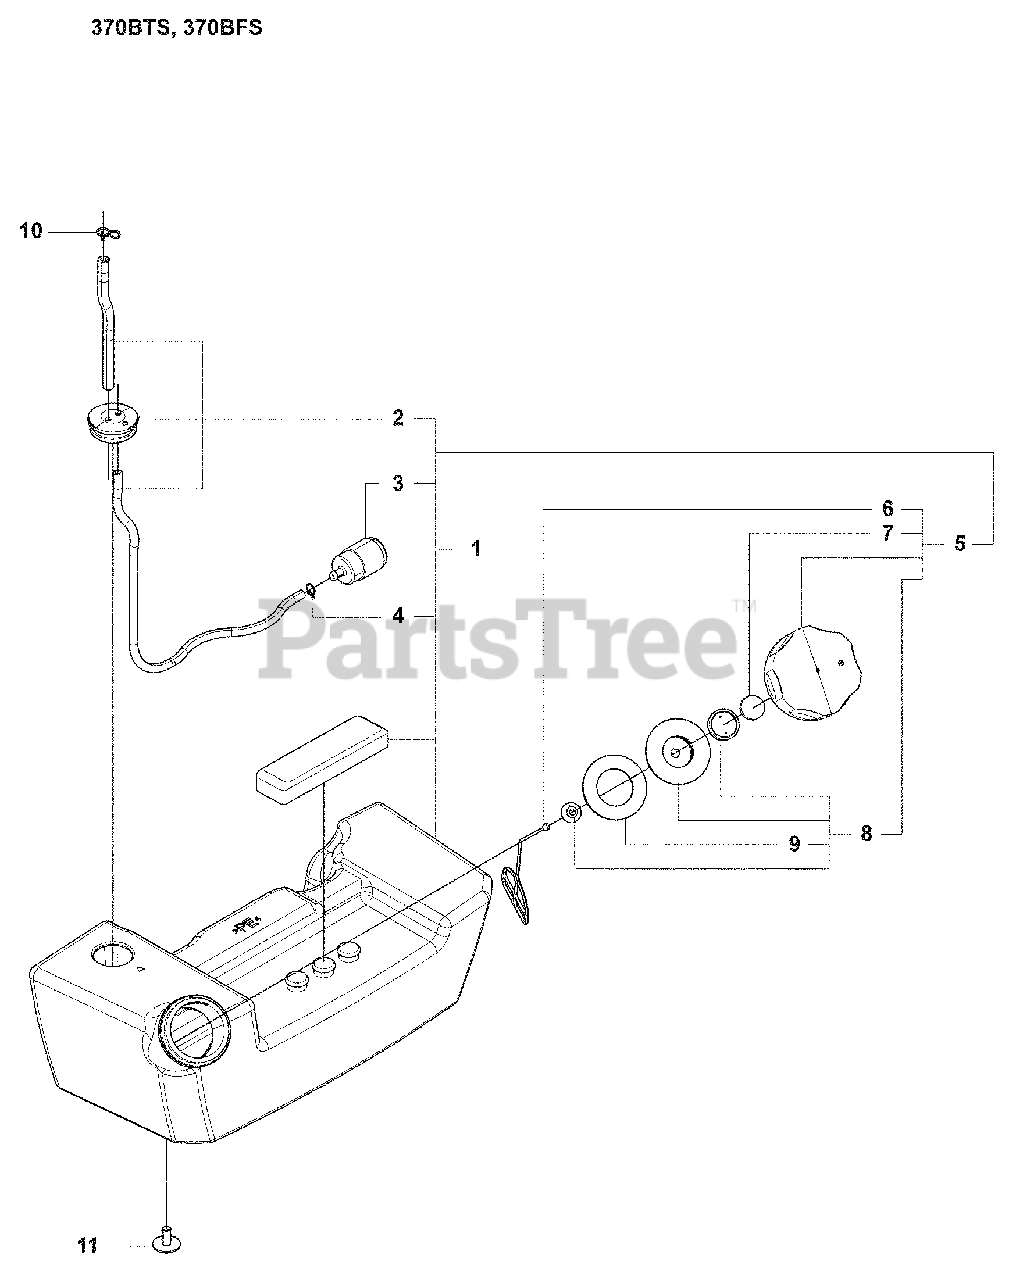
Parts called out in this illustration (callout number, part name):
2	Pipe, Complete
3	Fuel Filter Assembly
4	Clip
5	Cap, A
6	Stopper
7	Air Filter
8	Holder, A
9	Packing
10	Clip
